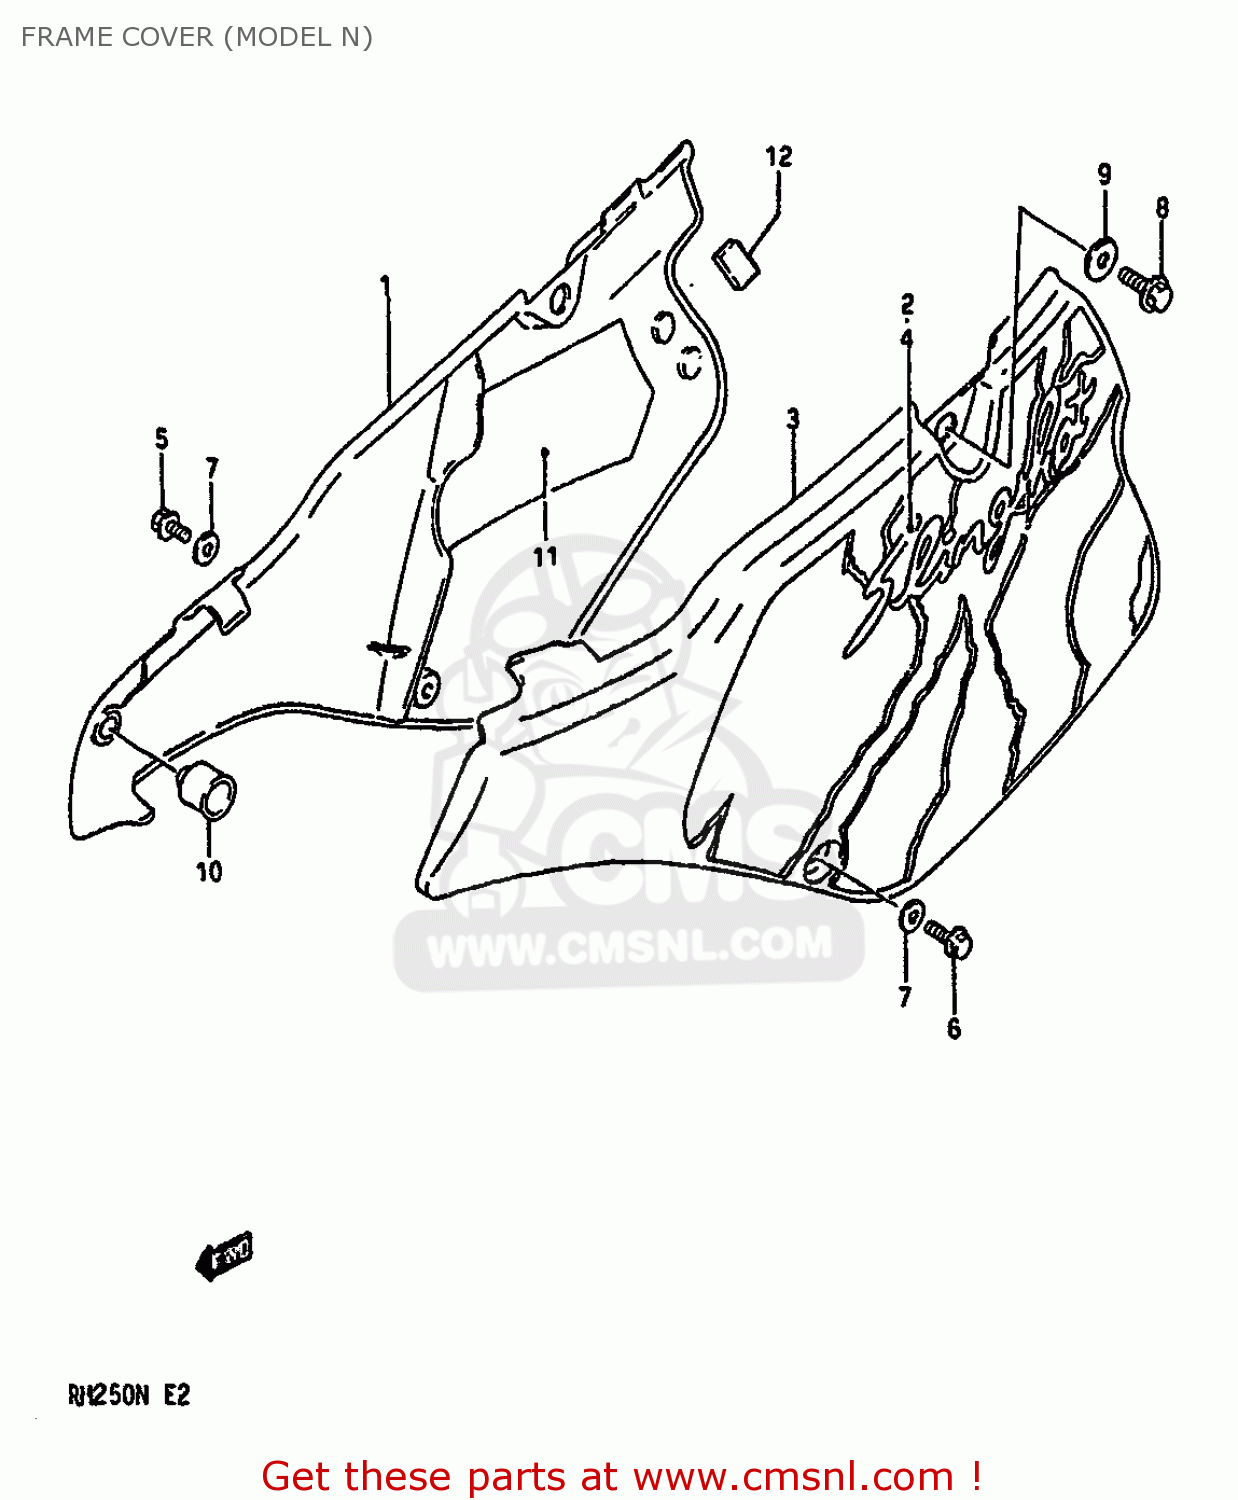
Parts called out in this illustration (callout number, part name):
1	COVER,FRAME,R(YELLOW)
2	TAPE SET,RH
3	COVER,FRAME,L(YELLOW)
4	TAPE SET,LH
5	BOLT
6	BOLT
7	GASKET(6.5X20X1.5) (NAS)
8	BOLT
9	WASHER
10	CUSHION
11	SHIELD,FRAME COVER,RIGHT
12	CUSHION,FRAME COVER,REAR
13	BOLT
14	WASHER
15	CUSHION
16	SHIELD,FRAME COVER,RIGHT
17	CUSHION,FRAME COVER,REAR
